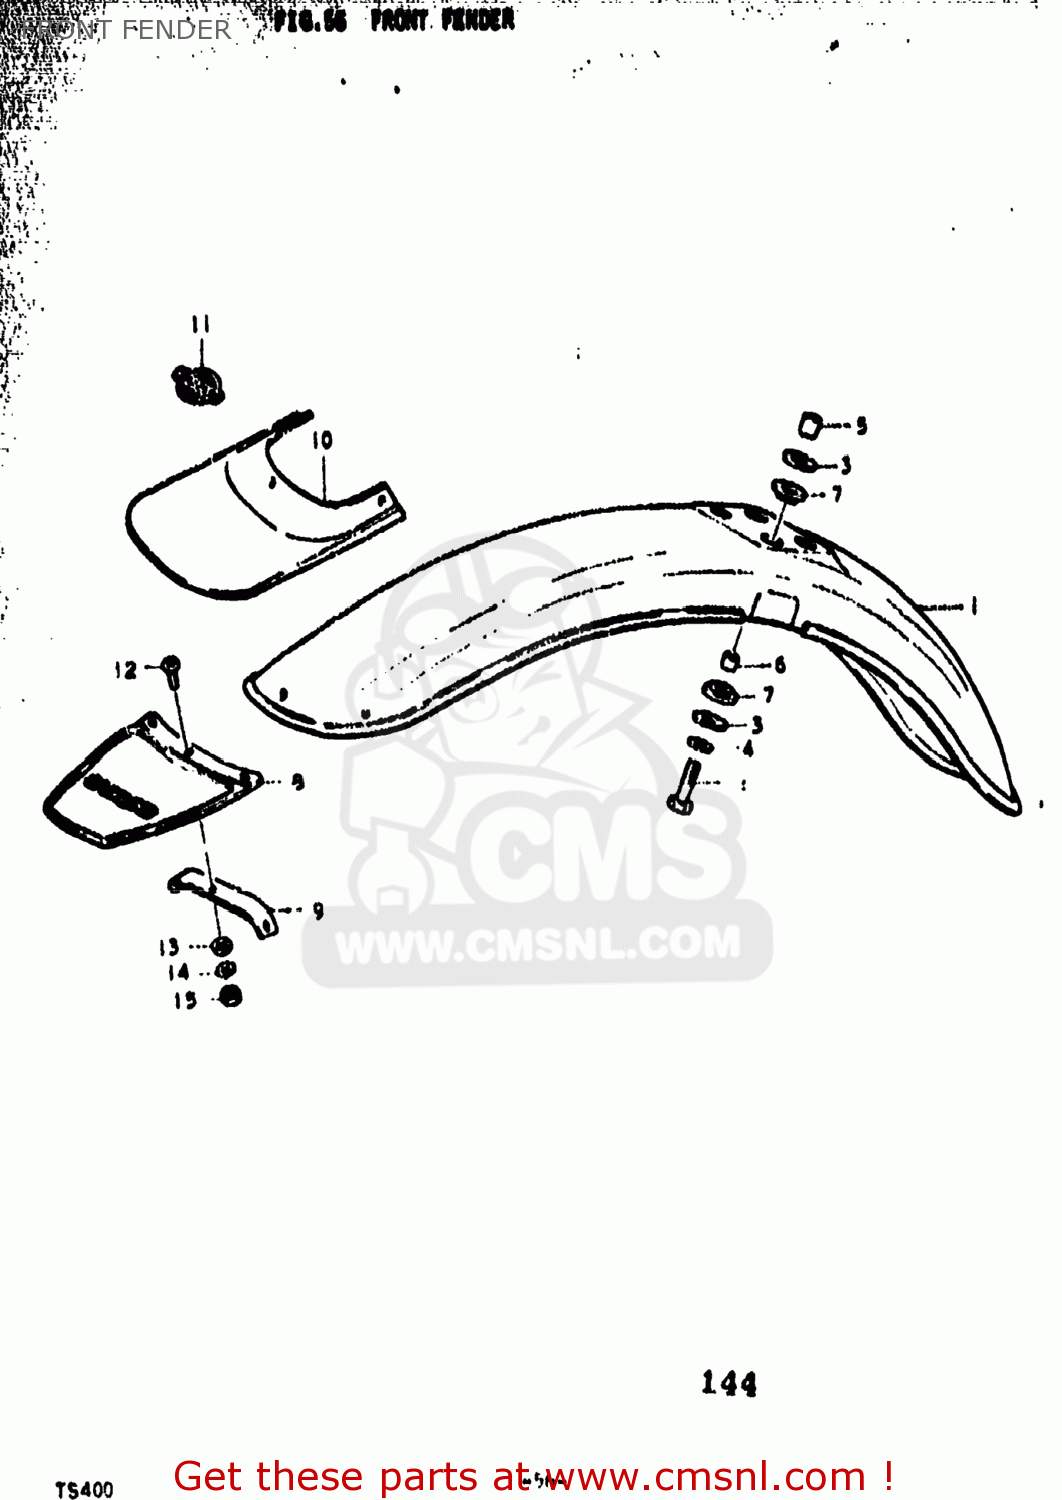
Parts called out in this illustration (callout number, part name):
1	FENDER,FRONT
2	BOLT
3	WASHER (6.5X24X1.2)
4	LOCK WASHER
5	SPACER
6	SPACER (6.5X10.5X13.5)
7	CUSHION
8	MUD FLAP,FRONT FENDER
9	PLATE, MUD FLAP K,L,M; OPT
10	MUD FLAP,FRONT FENDER
12	SCREW
13	WASHER
14	LOCK WASHER
15	NUT
